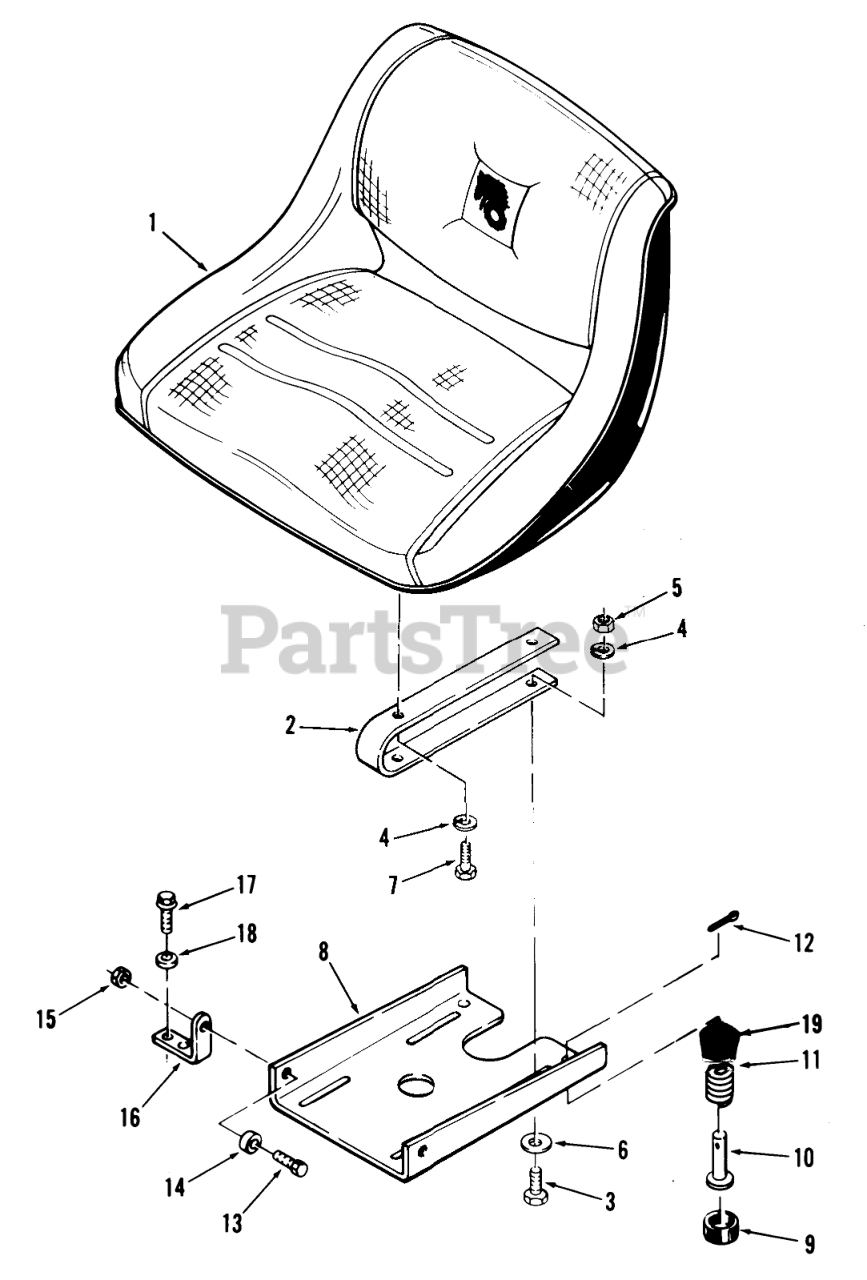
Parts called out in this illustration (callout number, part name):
1	Seat
2	Spring
3	HHCS
4	Lockwasher
5	Nut
6	Collar
7	Bolt
8	PLATE-SEAT PIVOT
11	SPRING
12	Cotter Pin
13	HHCS
14	BUSHING
15	Nut
16	BRACKET-PIVOT
17	Bolt
18	WASHER 5/16 SAE
19	NYLINER BUSHING
